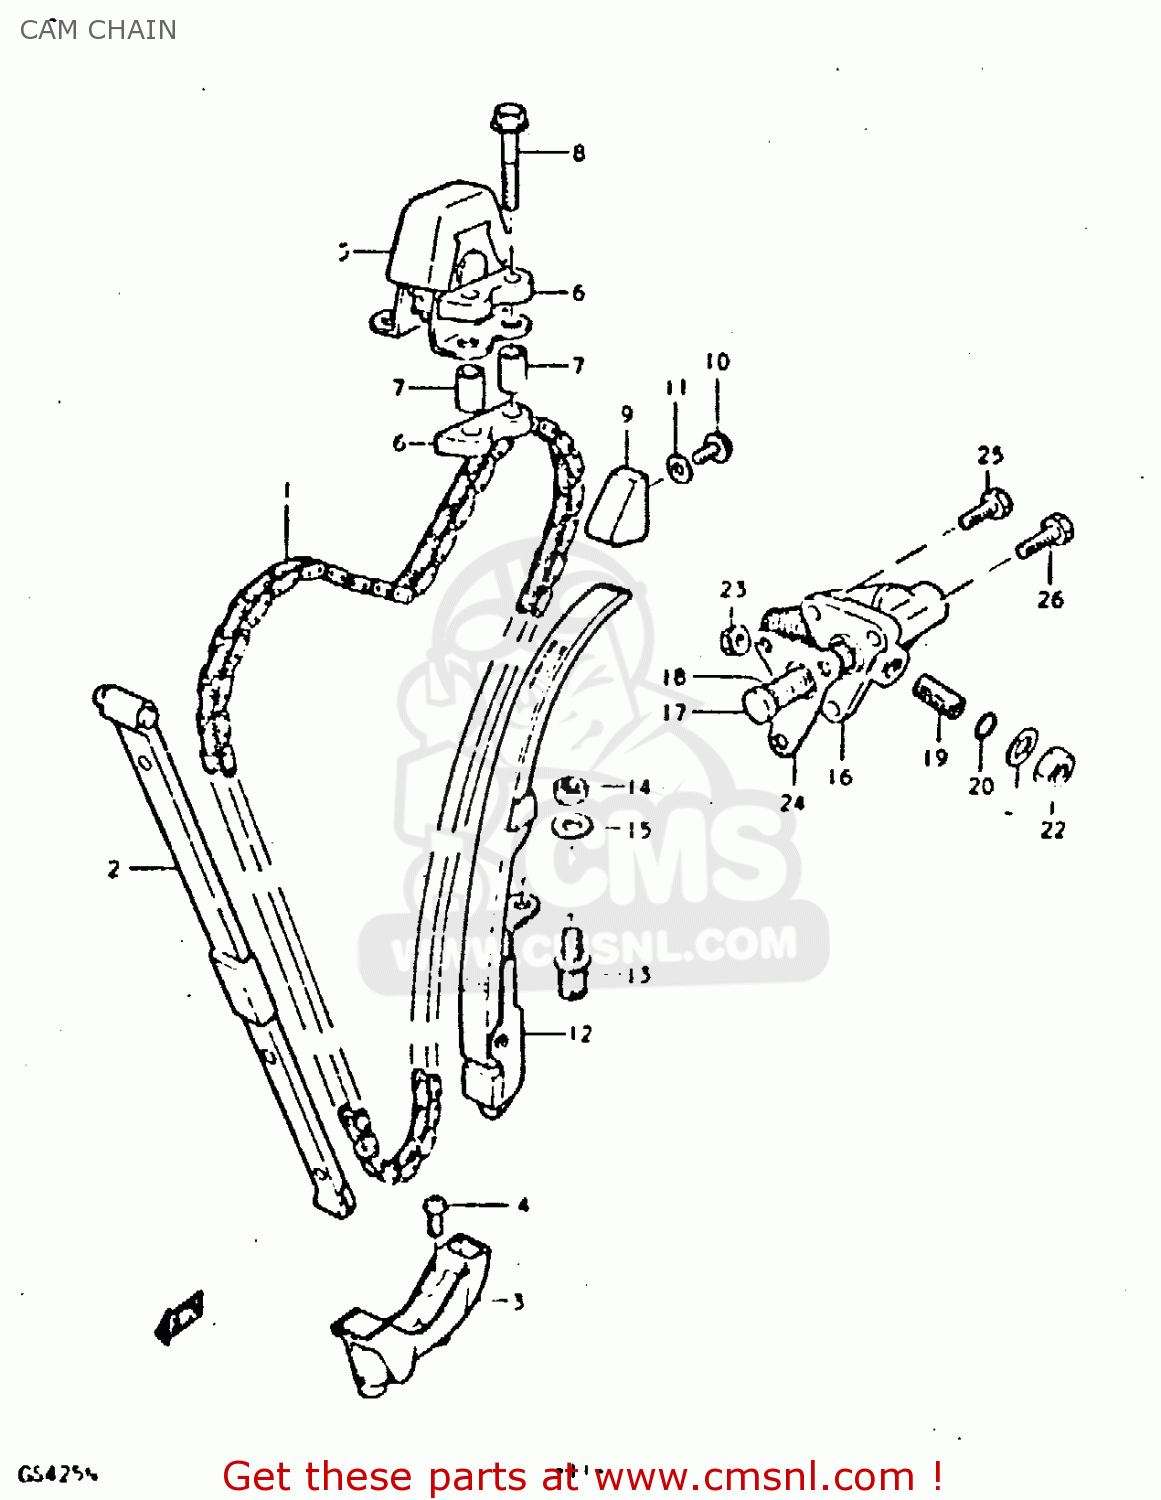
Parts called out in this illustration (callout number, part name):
1	CHAIN,CAMSHAFT DRIVE(120L)
2	GUIDE,CAM CHAIN
3	HOLDER,CAM CHAIN GUIDE
4	SCREW
5	IDLER,CAM CHAIN
6	CUSHION,IDLER
7	SPACER
8	BOLT
9	GUIDE,CAM CHAIN
10	BOLT
11	GASKET (NAS)
12	TENSIONER,CAM CHAIN
13	STUD
14	NUT 8MM
15	WASHER
16	ADJUSTER ASSEMBLY,TENSIONER
17	ROD,PUSH
18	SPRING
19	SCREW
20	O-RING
21	WASHER
22	NUT
23	NUT
24	GASKET,TENSIONER ADJUSTER (MCA)
25	SCREW
26	SCREW
